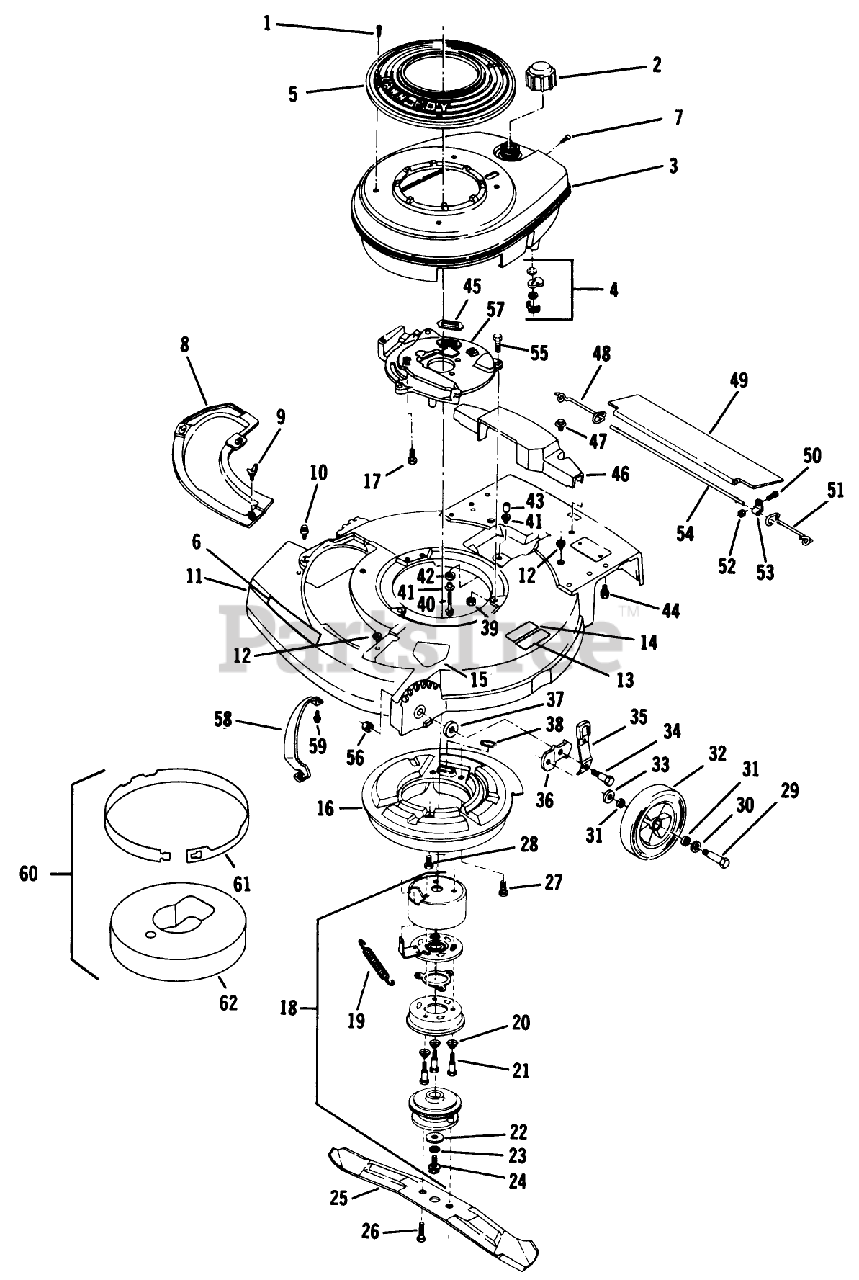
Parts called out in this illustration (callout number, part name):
1	SCREW - SELF TAPPING
2	FUEL CAP & INSERT
4	SHUT OFF VALVE KIT
7	SCREW S
9	WING SCREW LAWRE
13	PAD FOOT
17	SCREW V
19	SPRING
21	SCREW,SHOULDER SM
22	WASHER
26	SCREW SEMS
28	SCREW
29	BOLT WHEEL
30	SPACER
31	WASHER
32	WHEEL & TIRE KIT
33	WASHER WROUGHT
34	BOLT
37	WASHER
38	SEAL
39	NUT-LOCK F
41	SPACER ECK PRES
42	GROMMET
43	SPACER
44	SCREW
48	SPRING;TRAILING SHIELD RH
49	SHIELD
51	SPRIG T/SHLD ASOC
52	LOCKNUT E
53	CLAMP ROD KMC
54	ROD 21" ADVANCE
55	SCREW-HH
56	LOCKNUT
58	BAR-TOE
